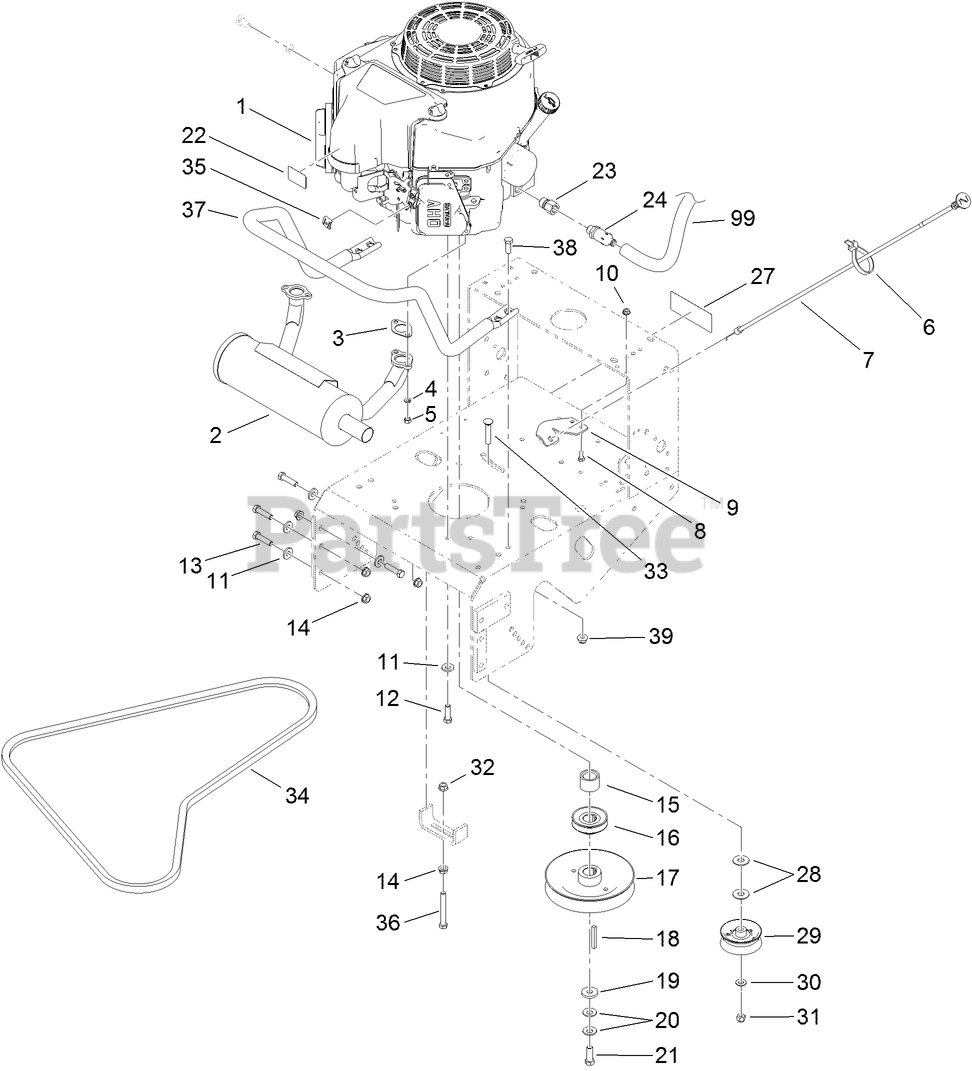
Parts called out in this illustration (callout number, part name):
2	MUFFLER-HORIZONTAL, OFFSET
3	GASKET-EXHAUST
4	WASHER-LOCK
6	TIE-CABLE
7	Cable-Choke
8	SCREW-HH
9	Bracket-Cable, Choke
10	NUT-HF
11	WASHER-BELLEVILLE
12	SCREW-HH
13	SCREW-HH
14	NUT-HHF, WHIZ
15	SPACER-CLUTCH
16	Sheave-Transmission
17	PULLEY ASM
19	WASHER
20	WASHER-SPRING
21	SCREW-HH
22	DECAL-CAUTION
23	Adapter
24	VALVE-DRAIN, OIL
27	DECAL-CAUTION
28	WASHER-FLAT
29	PULLEY-IDLER, FLAT
30	WASHER-FLAT
31	NUT-LOCK, NI
32	NUT-HF
33	SCREW-CARR
34	BELT-V
35	CLAMP-CABLE
36	SCREW-HH
37	GUARD-MUFFLER
38	SCREW-HH
39	NUT-HF, NI
99	HOSE-DRAIN, OIL
